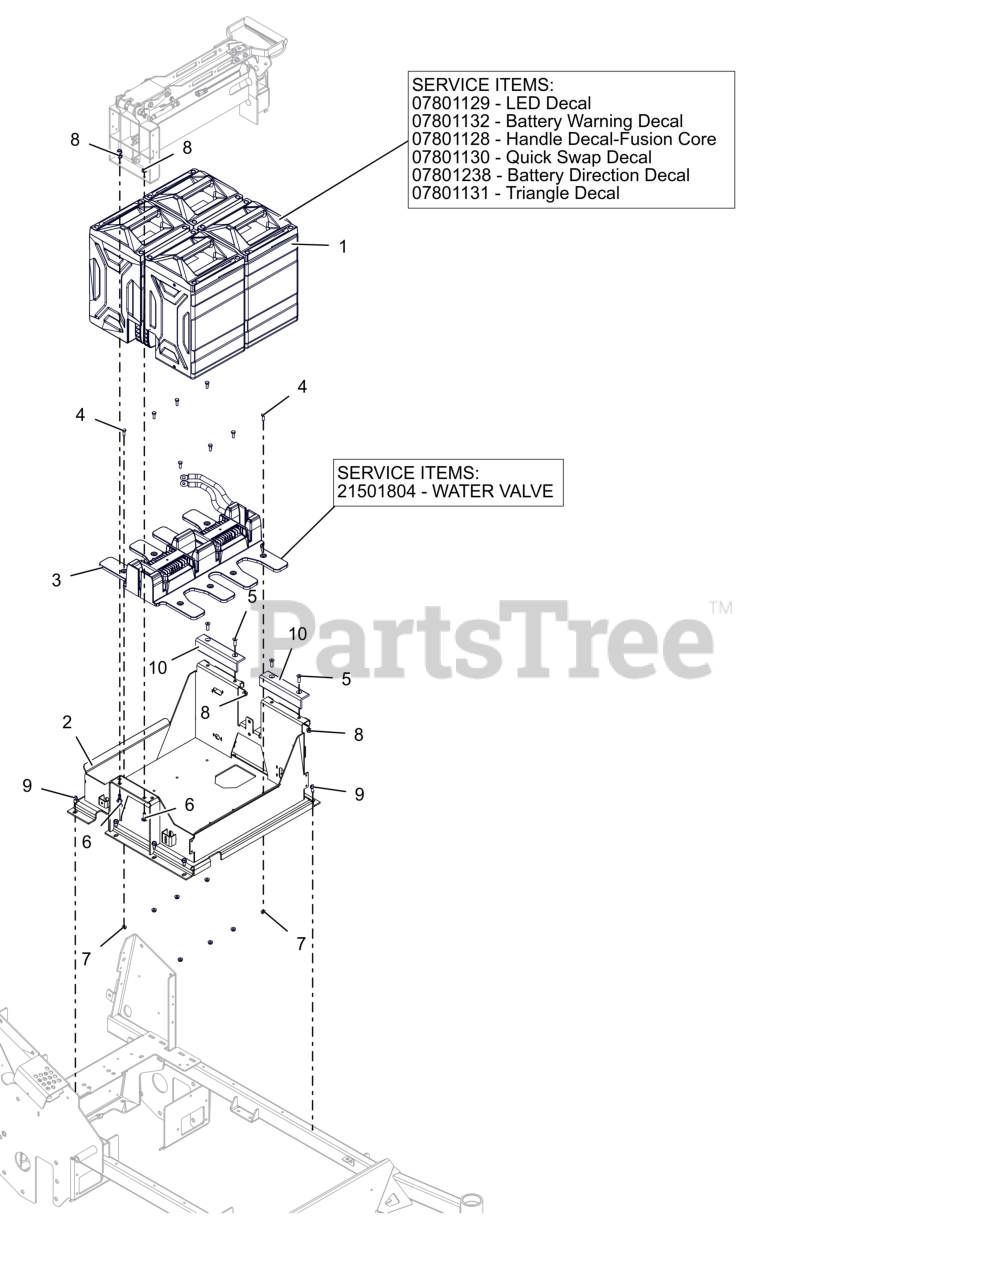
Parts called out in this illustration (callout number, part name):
1	KIT, EV BATTERY
1	LED DECAL
1	DECAL, BATTERY WARNING
1	HANDLE DECAL - FUSION CORE
1	DECAL, BATTERY QUICKSWAP
1	DECAL, BATTERY INSTALL DIRECTION
1	DECAL, BATTERY LED
2	WLDMT, BATTERY TRAY (ORANGE)
3	BASE, BATTERY BUSSBAR
3	VALVE, WATER
4	BLT, HEX .25-20X.75 G5 ZCC
5	SCR, MCH .312-18X1.00 SFH ZCC
6	BLT,RHSN .31-18X1.00 G5 ZCC
7	NUT-LK-CTR-FLG .25-20 ZC120
8	NUT,LK-CTR-FLG .31-18 GF ZCC
9	SCR,TAP .312-18X.75 HWH TR ZCC
10	EDGE, PROTECTIVE - BATTERY
